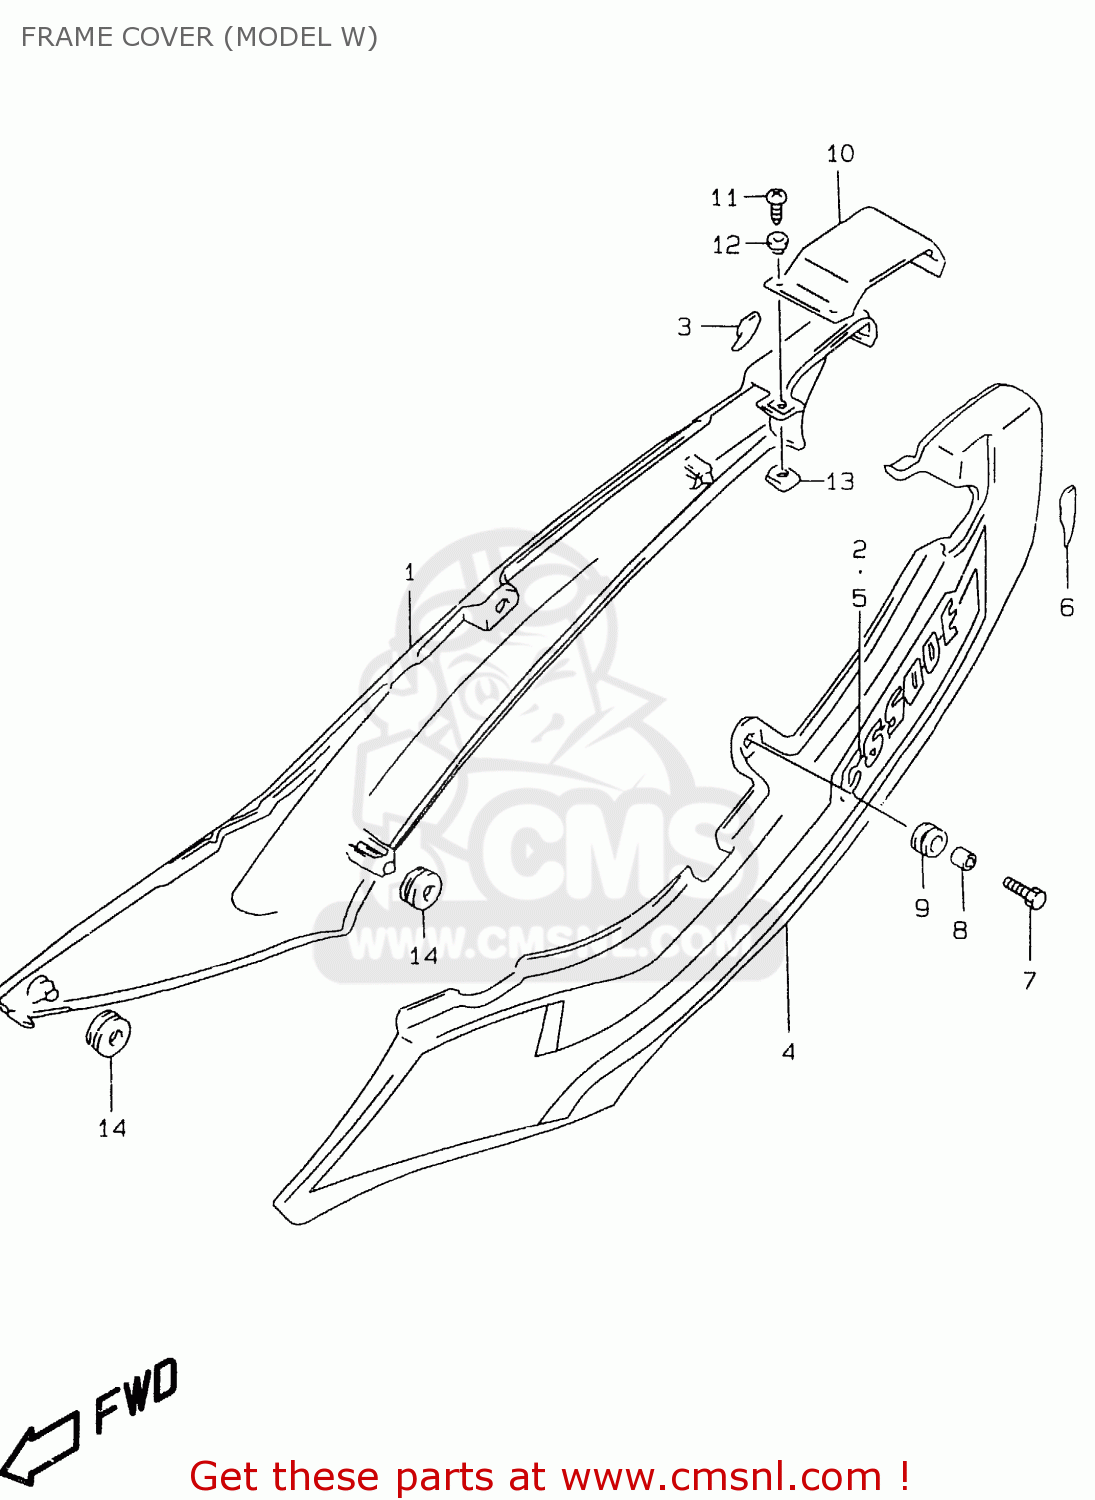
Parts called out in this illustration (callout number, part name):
1	COVER,FRAME,R(BLACK)
2	TAPE,FRAME COVER,R
3	PROTECTOR,FRAME COVER,R
4	COVER,FRAME,L(BLACK)
5	TAPE,FRAME COVER,L
6	PROTECTOR,FRAME COVER,L
7	BOLT(6X20)
8	SPACER(6.5X9X9)
9	CUSHION
10	COVER,FRAME CTR
11	SCREW L:12
12	WASHER(5.2X14X1.5)
13	NUT
14	CUSHION
